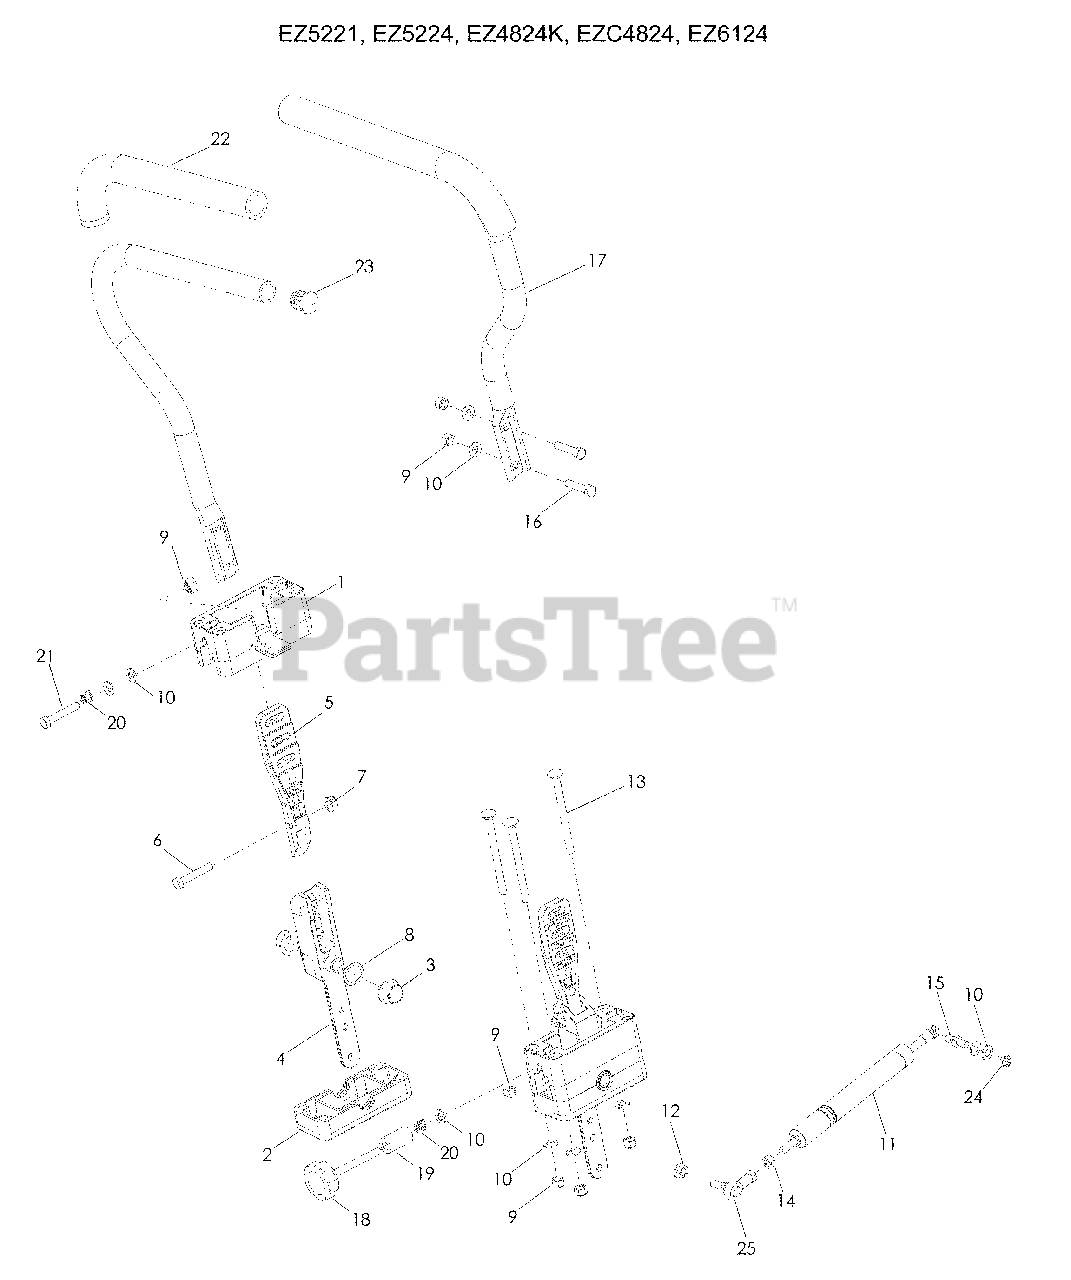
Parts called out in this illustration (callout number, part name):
1	BLOCK, UPPER
2	BLOCK, LOWER
3	BEARING, FLANGE
4	PIVOT SECTION, DRIVE
5	MOUNT, DRIVE CONTROL
6	HCS 5/16-18 x 1¾
7	NUT 5/16-18 FLANGE NYLOC
8	WASHER, .825 x 1.087 WAVE
9	NUT 5/16-18 HEX NYLOC
10	WASHER 5/16 SAE FLAT
11	DAMPENER w/SPRING
12	NUT 5/16-18 HEX WHIZLK
13	RHSNB 5/16-18 x 4
14	NUT M8 x 1½ HEX
15	BALL STUD 10mm
16	HCS 5/16-18 x 1½
17	LEVER, w/GRIP
21	HCS 5/16-18 x 2 TPBLT
22	GRIP, FOAM
24	NUT 5/16-18 HEX NYLOC
